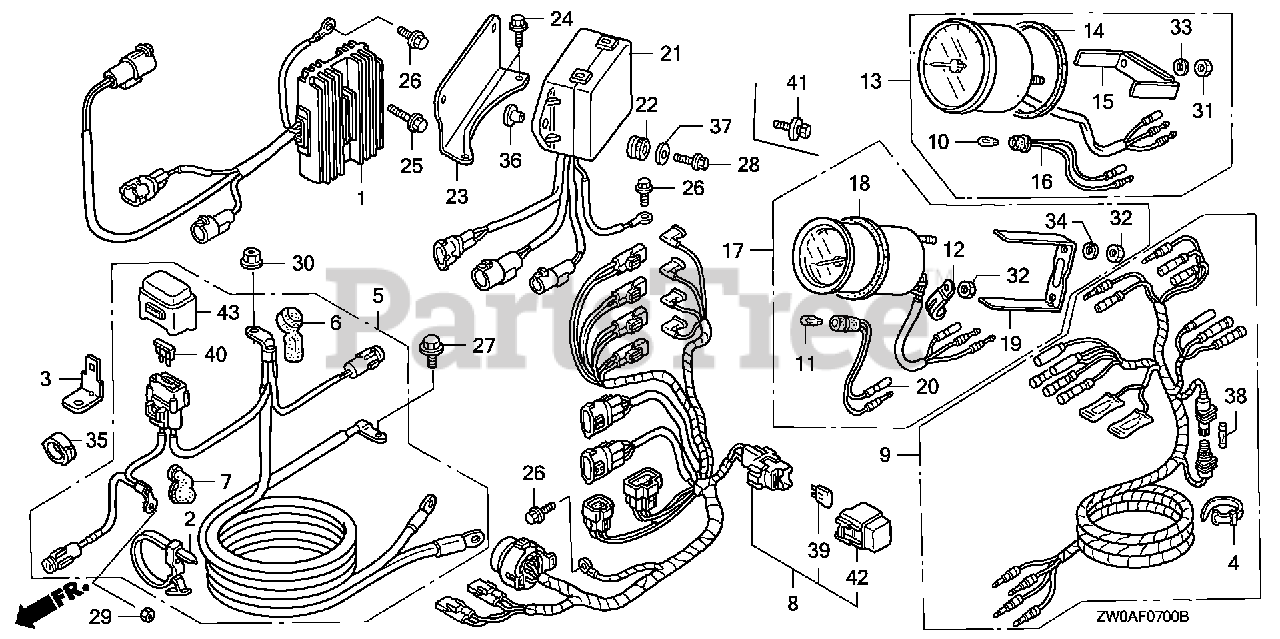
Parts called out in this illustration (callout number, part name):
1	RECTIFIER ASSY., REGULATOR (20A)
2	BAND, WIRE
3	BRACKET, FUSE
4	BAND B1, WIRE
5	CABLE ASSY., STARTER
6	COVER, STARTER TERMINAL
7	COVER, MAGNETIC SWITCH TERMINAL
8	CABLE ASSY., REMOTE CONTROL (A)
9	HARNESS ASSY., METER (A)
10	BULB, WEDGE BASE (T10) (12V 1.7W) (STANLEY)
13	TACHOMETER ASSY.
21	RELAY ASSY., POWER TILT
22	GROMMET, RELAY
23	BRACKET, RELAY
24	BOLT, FLANGE (6X14) (CT200)
25	BOLT, FLANGE (6X22) (CT200)
26	BOLT, FLANGE (6X12) (CT200)
27	BOLT, FLANGE (6X14)
28	BOLT, FLANGE (6X25)
29	NUT, HEX. (6MM)
30	NUT-WASHER (8MM)
31	NUT, HEX. (5MM)
33	WASHER, SPRING (5MM)
35	CLIP, WIRE HARNESS
36	COLLAR, MODULE IGNITION CONTROL CASE (CDI)
37	WASHER, PLAIN (6MM)
38	FUSE A (10A)
39	FUSE, BLADE (15A)
40	FUSE, BLADE (30A)
41	BOLT-WASHER (6X25)
42	COVER ASSY., FUSE (15A)
43	COVER ASSY., FUSE (30A)
